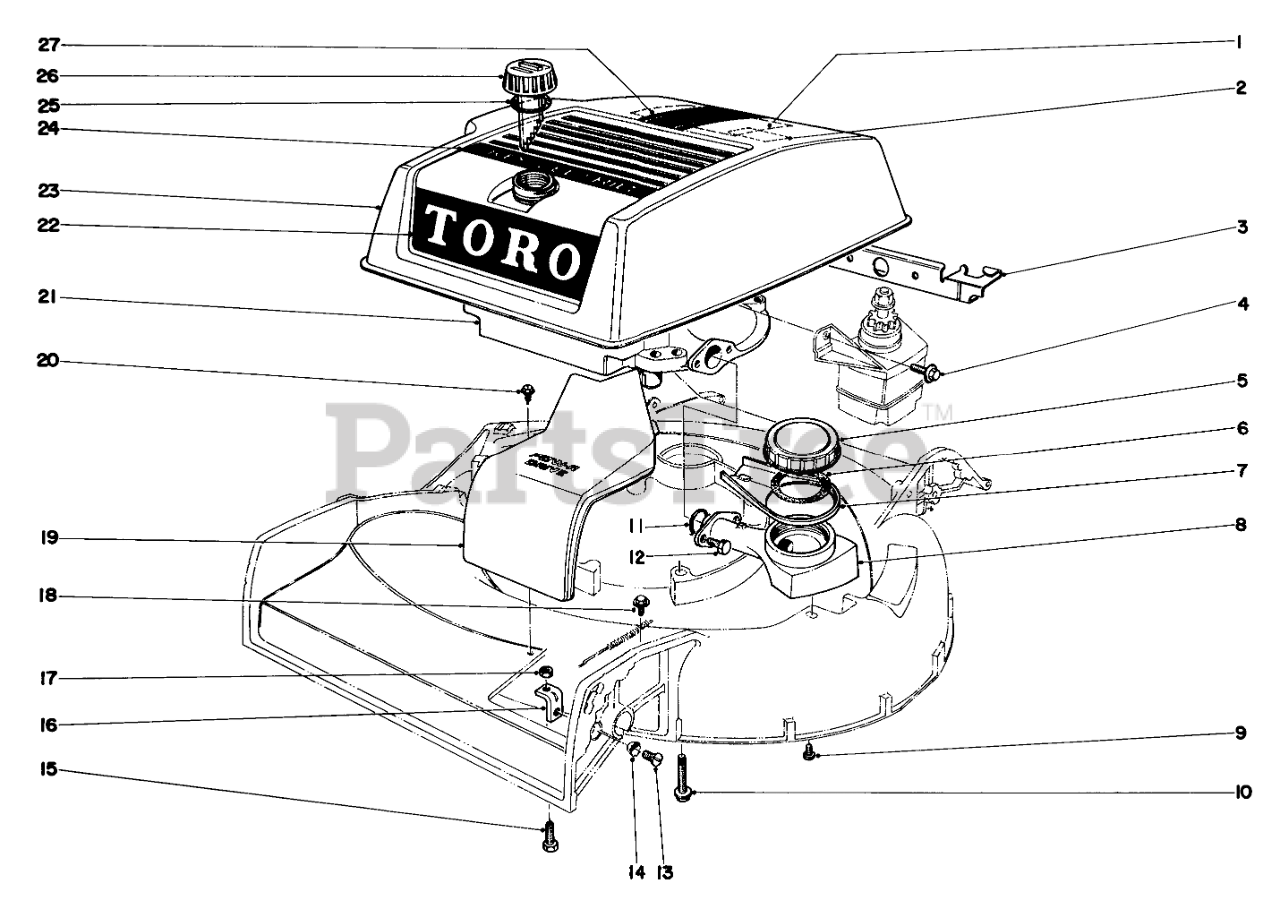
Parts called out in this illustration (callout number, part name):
1	Decal-Maintenance
2	Decal Caution
3	Shroud Bracket
4	SCREW
5	Oil Gauge Cap
6	VISUAL OILER GASKET
7	Spout
8	Oil Gauge
9	Screw
10	3/8-16 X 2-3/4 CAPSCR
11	O RING
12	SCREW-HH
14	Lockwasher
15	SCREW
16	ADJ BRACKET
17	NUT-JAM
18	Screw
19	Cover
20	SCREW-HWHTF
21	Engine
22	Decal-Toro
23	Shroud
24	Decal-Key-Lectric
25	Gasket
26	Gas Cap
27	Decal
